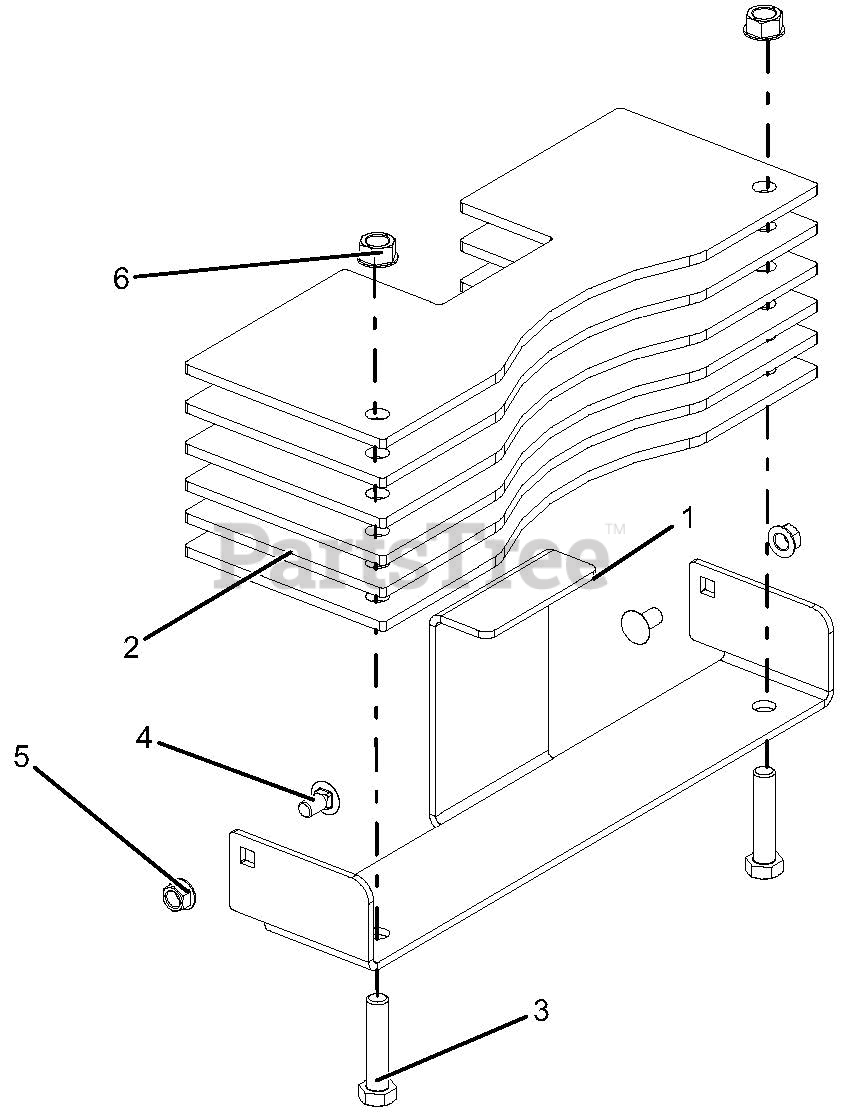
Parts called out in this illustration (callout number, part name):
1	BRKT, WEIGHT HANGING- BAGGER
2	WEIGHT, BAGGER
3	BLT-HEX .50-13X2.25 GR5 YWZC
4	BLT-RDHDSQNK .38-16X.75 G5 YWZC
5	NUT, LK-TOP-FLG .38-16 YWZC
6	NUT, LK-TOP-FLG .50-13 YWZC
